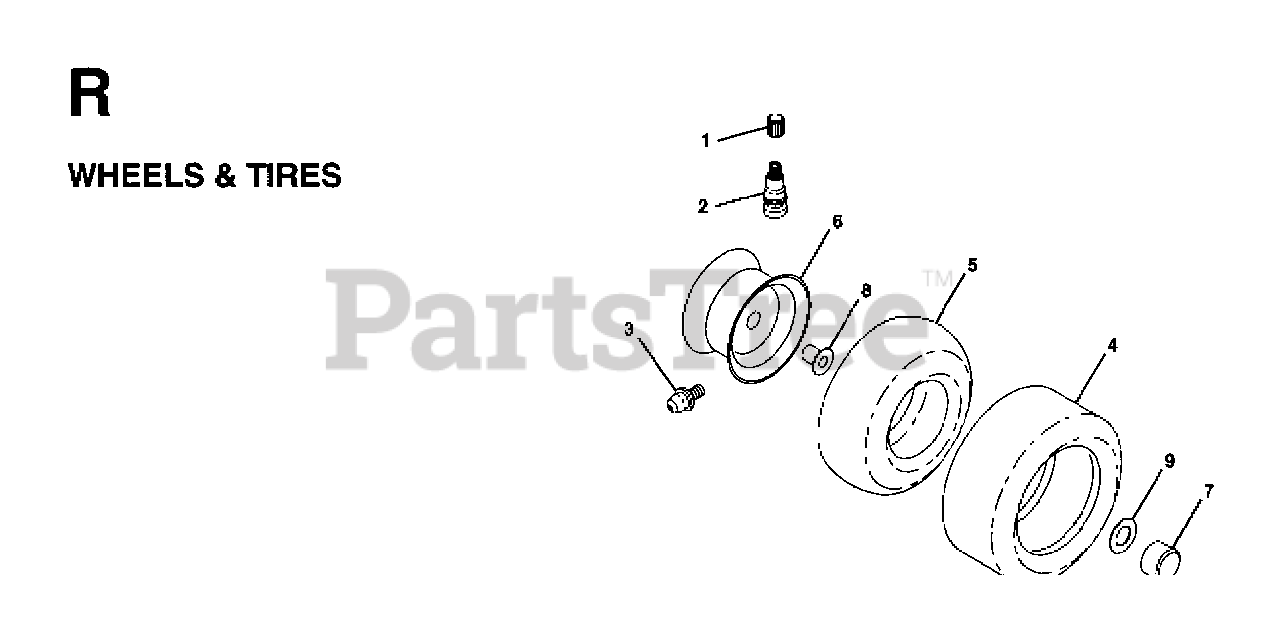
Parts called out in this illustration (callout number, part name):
1	VALVE CAP
2	VALVE STEM LT
3	FITTING LT
4	TIRE FRONT 15X6-6
4	REAR TIRE
5	TUBE.5.3/4.5/6
5	TUBE.16X6.5/7.5-8
6	RIM
6	RIM REAR 8"
7	CAP-HUB FRONT LT
8	BEARING T
